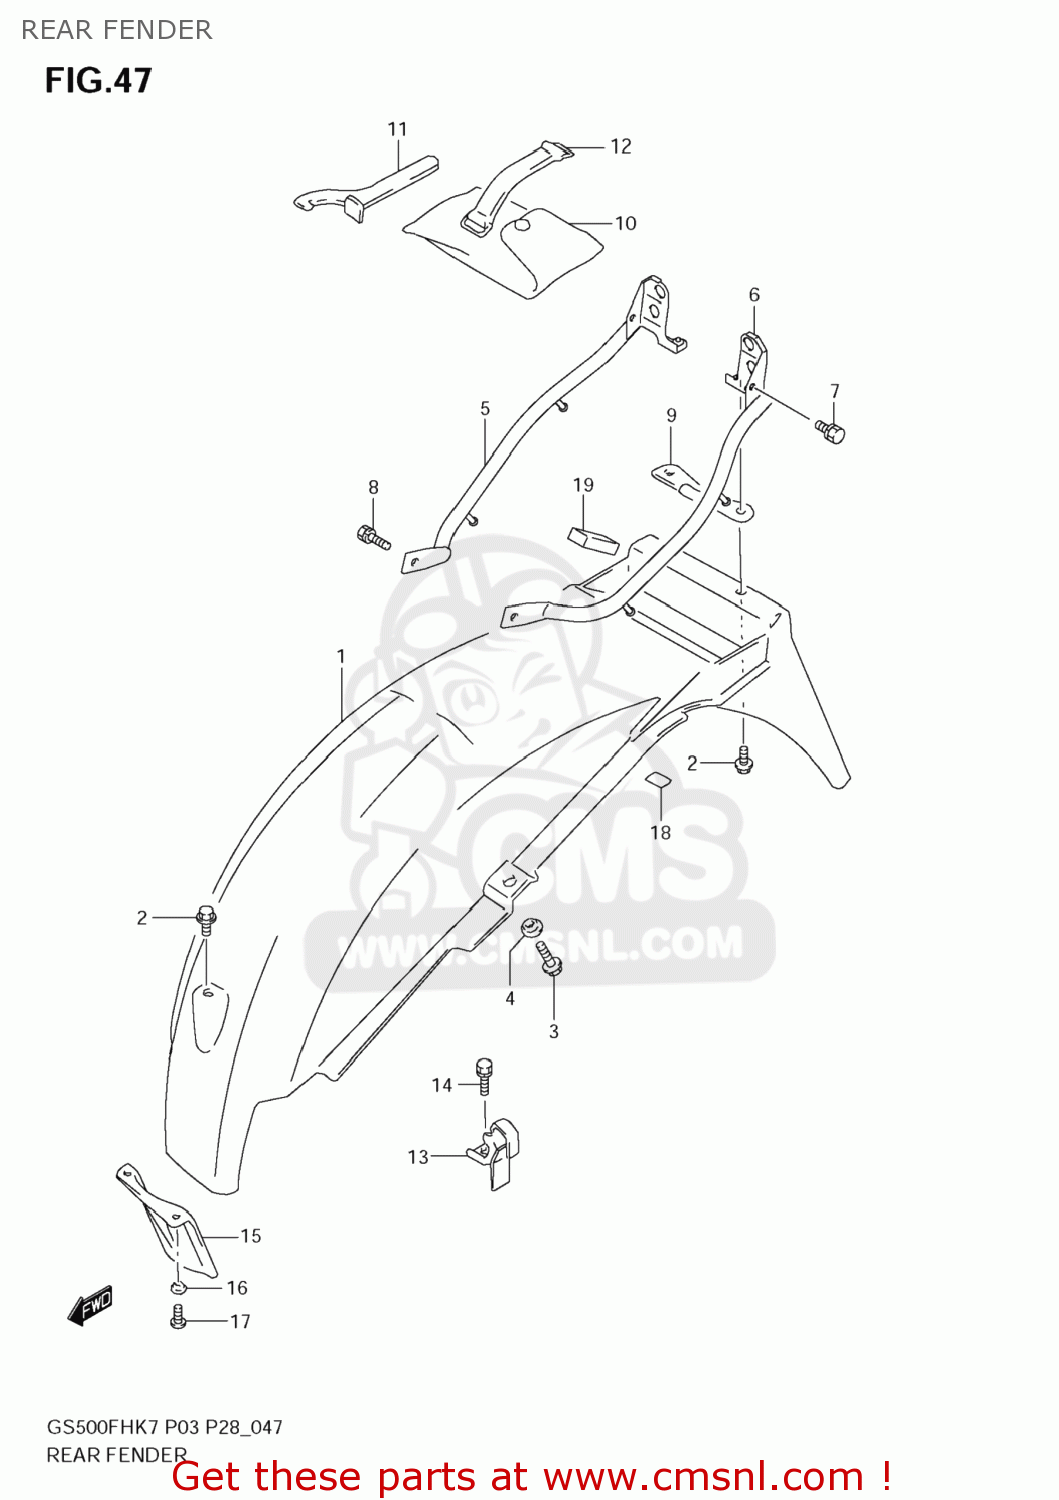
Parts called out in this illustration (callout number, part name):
1	FENDER
2	BOLT(6X16)
3	BOLT UH125&200
4	WASHER
5	BRACE,RR FENDER,R
6	BRACE,RR FENDER,L
7	BOLT
8	BOLT
9	PLATE,TOOL HOLDER
10	TOOL ASSY
11	CLAMP, WRENCH
12	O RING(D:3.53,ID:69.44)
13	HOLDER,HELMET
14	BOLT UH125&200
15	MUD GUARD, REAR UNIT
16	WASHER
17	SCREW
18	TAPE, REAR FENDER
19	PROTECTOR(20X50X11)
